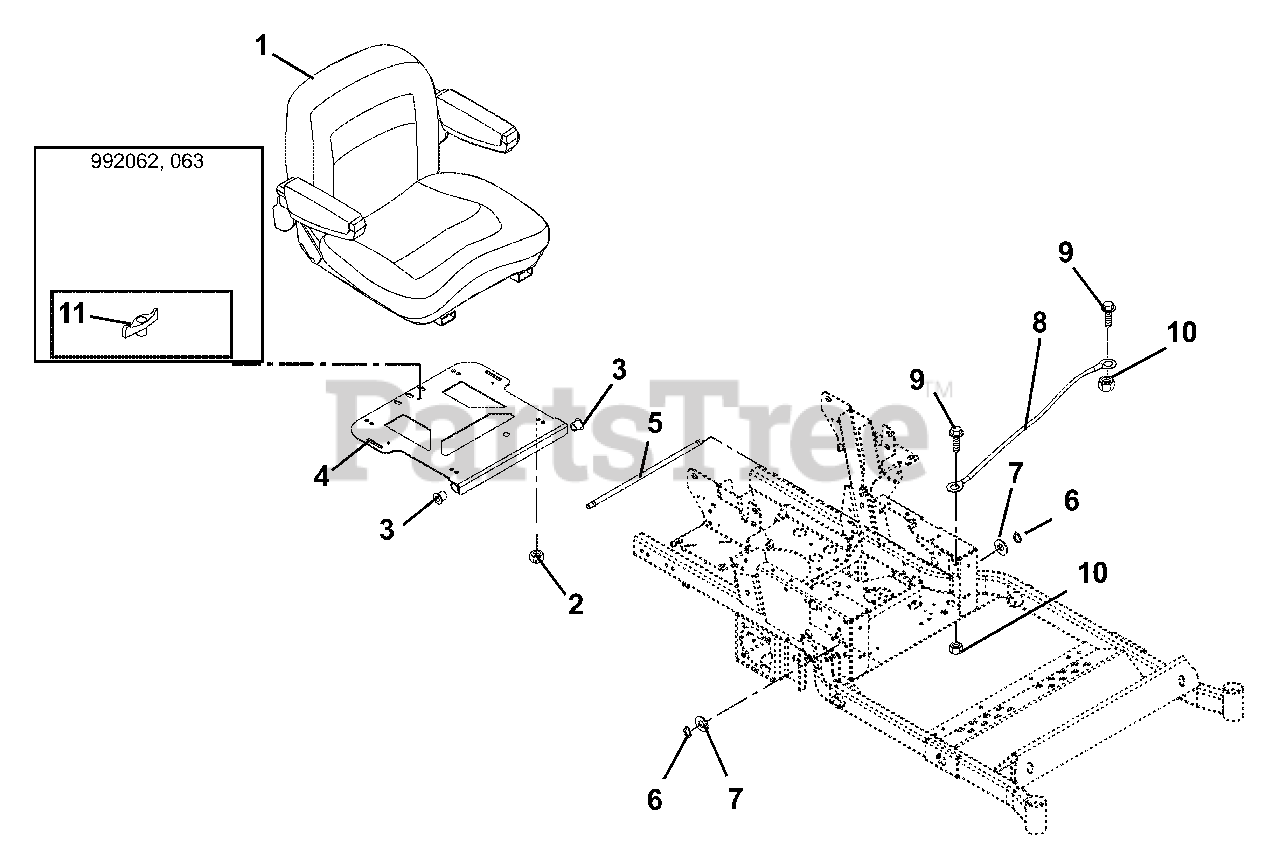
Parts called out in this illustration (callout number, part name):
1	SEAT, MILSCO XB180 - ZOOM
2	@NUT-LK-TOP-FLG .31-18 YWZC
3	BSHG-FLG .515X.750X.745X1.00NY
4	WMT, SEAT PIVOT MOUNT
5	ROD, SEAT FRAME PIVOT
6	RG-RTNG-EXT .500X.050 (SNAP)
7	WSHR-FL-STL.531X1.00X.063 YWZC
8	CBL,HOOD
9	@BLT-HEX .25-20X.75 GR5 YWZC
10	@NUT-LK-TOP-FLG .25-20 YWZC
11	KNOB - WING .312-18 UNC
